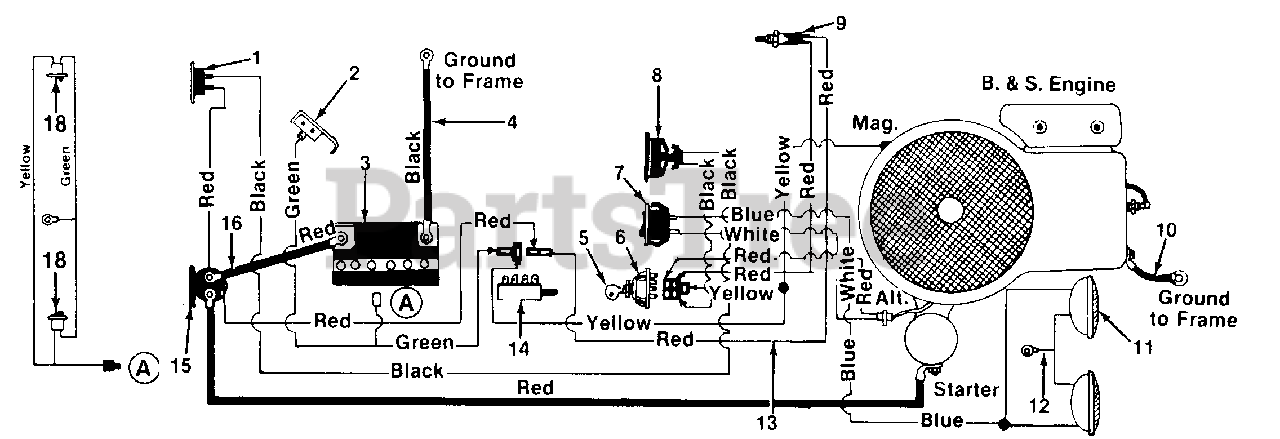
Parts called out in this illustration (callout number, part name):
1	Circuit Breaker
2	Spring Switch
3	12V-Battery
4	Grounding Wire 9.0" Lg.
5	Ignition Key
6	Ignition Switch
7	Headlight Switch
8	Ammeter
9	Safety Switch
10	Ground Wire 7.25" Lg.
11	Headlight
12	Ground Wire
13	Wire Harness
14	Safety Switch
15	Solenoid
16	Electric Wire w/Boot
18	Safety Switch
